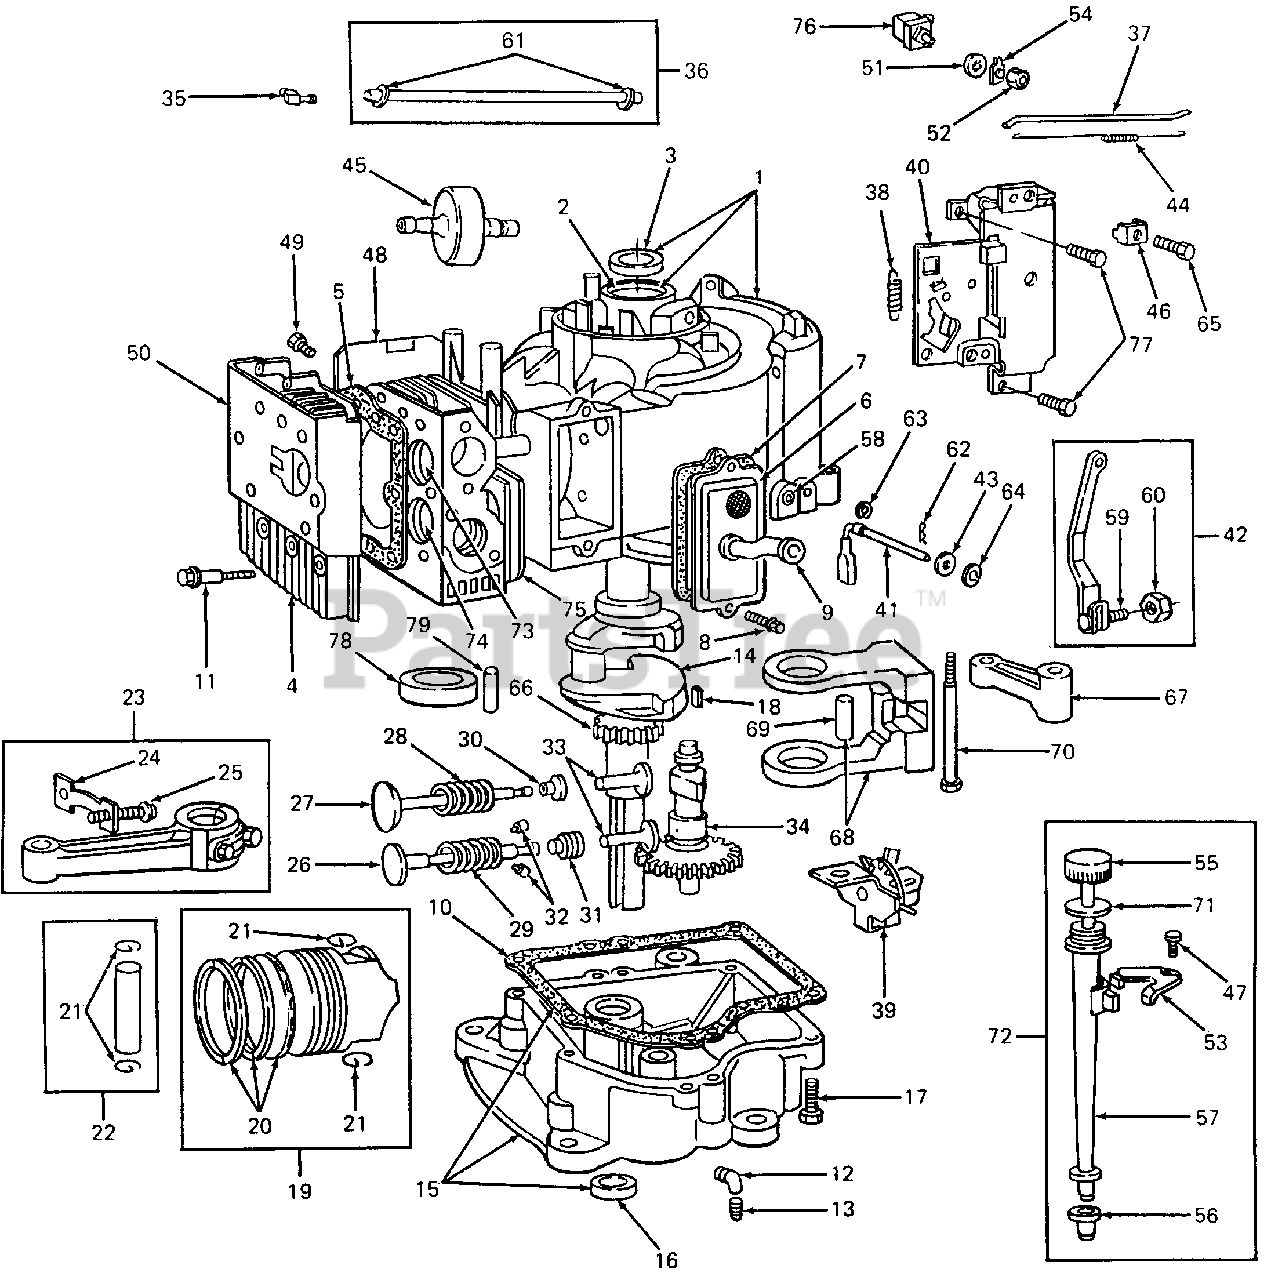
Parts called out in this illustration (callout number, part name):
1	Cylinder Assembly
2	Bearing, Cylinder
3	Seal, Oil
4	Head, Cylinder
5	Gasket, Cylinder Head
6	Breather Assembly
7	Gasket, Valve Cover
8	Screw, Sems
9	Tube, Breather
10	Gasket, Crankcase Cover, 1/64" Thk
11	Screw, Cylinder Head
12	Tube, Oil Drain
13	Plug, Oil Drain
14	Crankshaft
15	Sump, Engine
16	Seal, Oil
17	Screw, Sump Mounting Sems
18	Key, Flywheel
19	Piston Assy, Std
20	Ring Set, Piston, Std
21	Lock, Piston Pin
22	Pin, Assembly, Piston, Std
23	Rod Assembly, Connecting
24	Lock, Connecting Rod Screw
25	Screw, Connecting Rod
26	Valve, Exhaust
27	Valve, Intake
28	Spring, Intake Valve
29	Spring, Exhaust Valve
30	Retainer, Intake Valve
31	Rotocoil, Exhaust Valve
32	Retainer, Exhaust Valve Rotocoil
33	Tappet, Valve
35	Connector, Elbow
36	Line, Fuel
37	Link, Governor
38	Spring, Governor
39	Oil Slinger, Governor Gear & Bracket Assembly
40	Plate, Governor Control
41	Crank, Governor
42	Lever Assy, Governor
43	Washer, Governor Crank
44	Spring, Governor Link
45	Filter, Fuel
46	Clamp, Casing
47	Screw, Clamp Mounting
48	Shield, Cylinder
49	Screw, Cylinder Shield Mtg Sems
50	Cover, Cylinder Head
51	Washer, Lock
52	Nut, Hex, #8-32
53	Clamp, Oil Filler Tube
54	Terminal, Spade
55	Cap & Dipstick, Oil Filler
56	Seal, Filler Tube
57	Tube, Oil Filler
58	Bushing, Governor Crank
59	Bolt, Governor Lever
60	Nut, Hex, #10-24
61	Clamp, Fuel Pipe
62	Cotter, Hair Pin
63	Retainer, E-Ring
64	Seal, Oil
65	Screw, Sems
66	Gear, Timing
67	Link, Counterweight
68	Counterweight Assembly
69	Pin, Counterweight
70	Screw, Counterweight
71	Seal, Oil Filler Cap
72	Fill Group, Oil
73	Seat, Intake Valve Std
74	Seat, Exhaust Valve Std
75	Guide, Exhaust Valve
76	Insulator Assy
77	Screw, Carburetor
79	Pin, Eccentric
